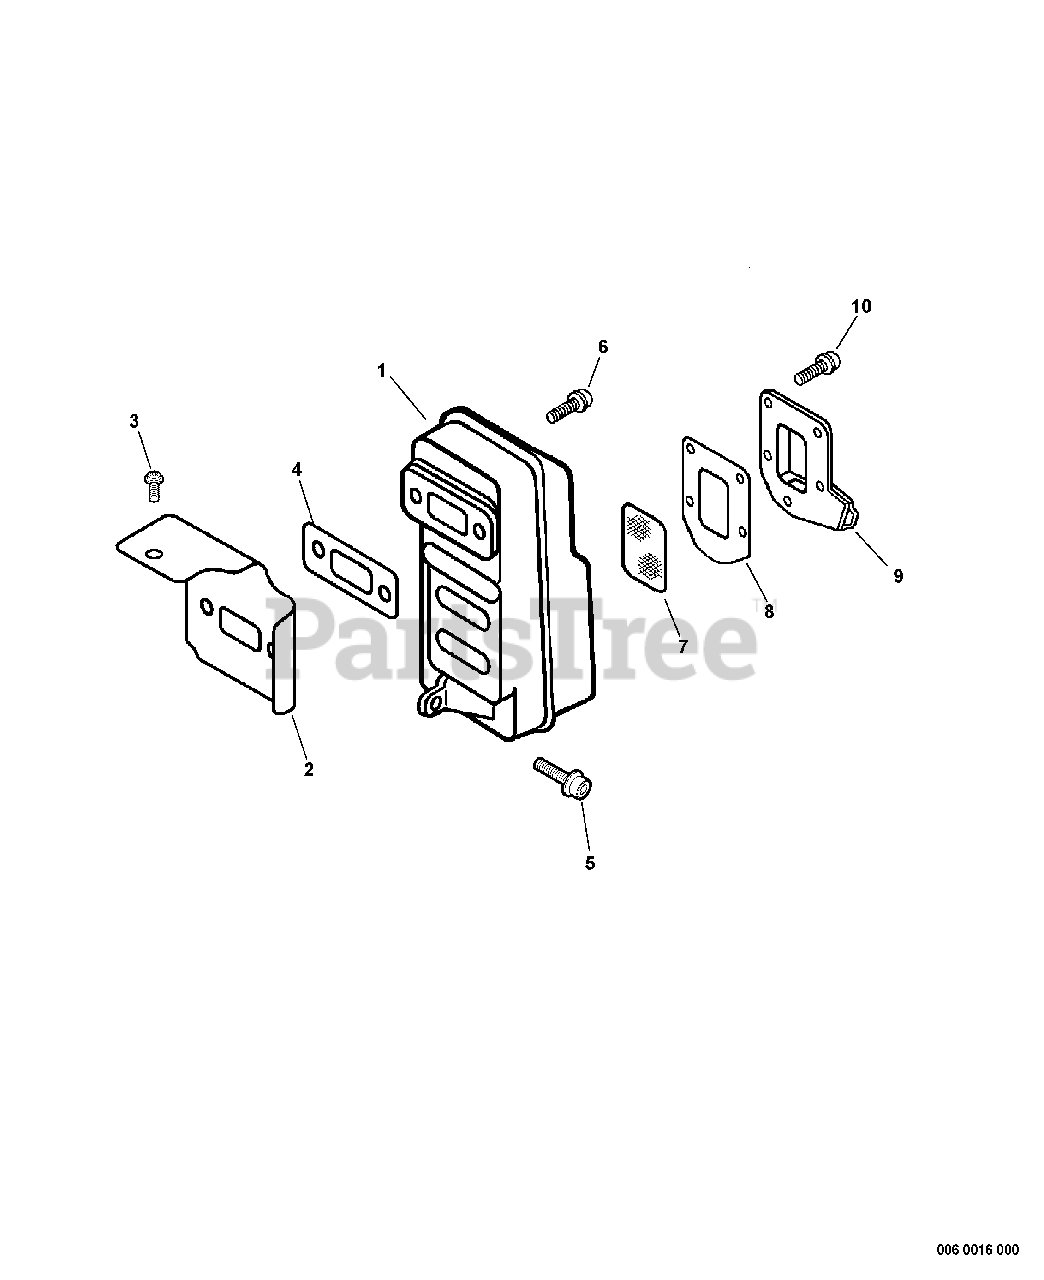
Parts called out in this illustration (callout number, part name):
1	MUFFLER
2	SHIELD, CYLINDER - EXHAUST
3	SCREW - 5X10
4	GASKET, EXHAUST
5	SCREW - 5X20
6	SCREW - 6X20
7	SCREEN, SPARK ARRESTOR
8	GASKET, EXHAUST
9	GUIDE, EXHAUST
10	SCREW - 4X10
